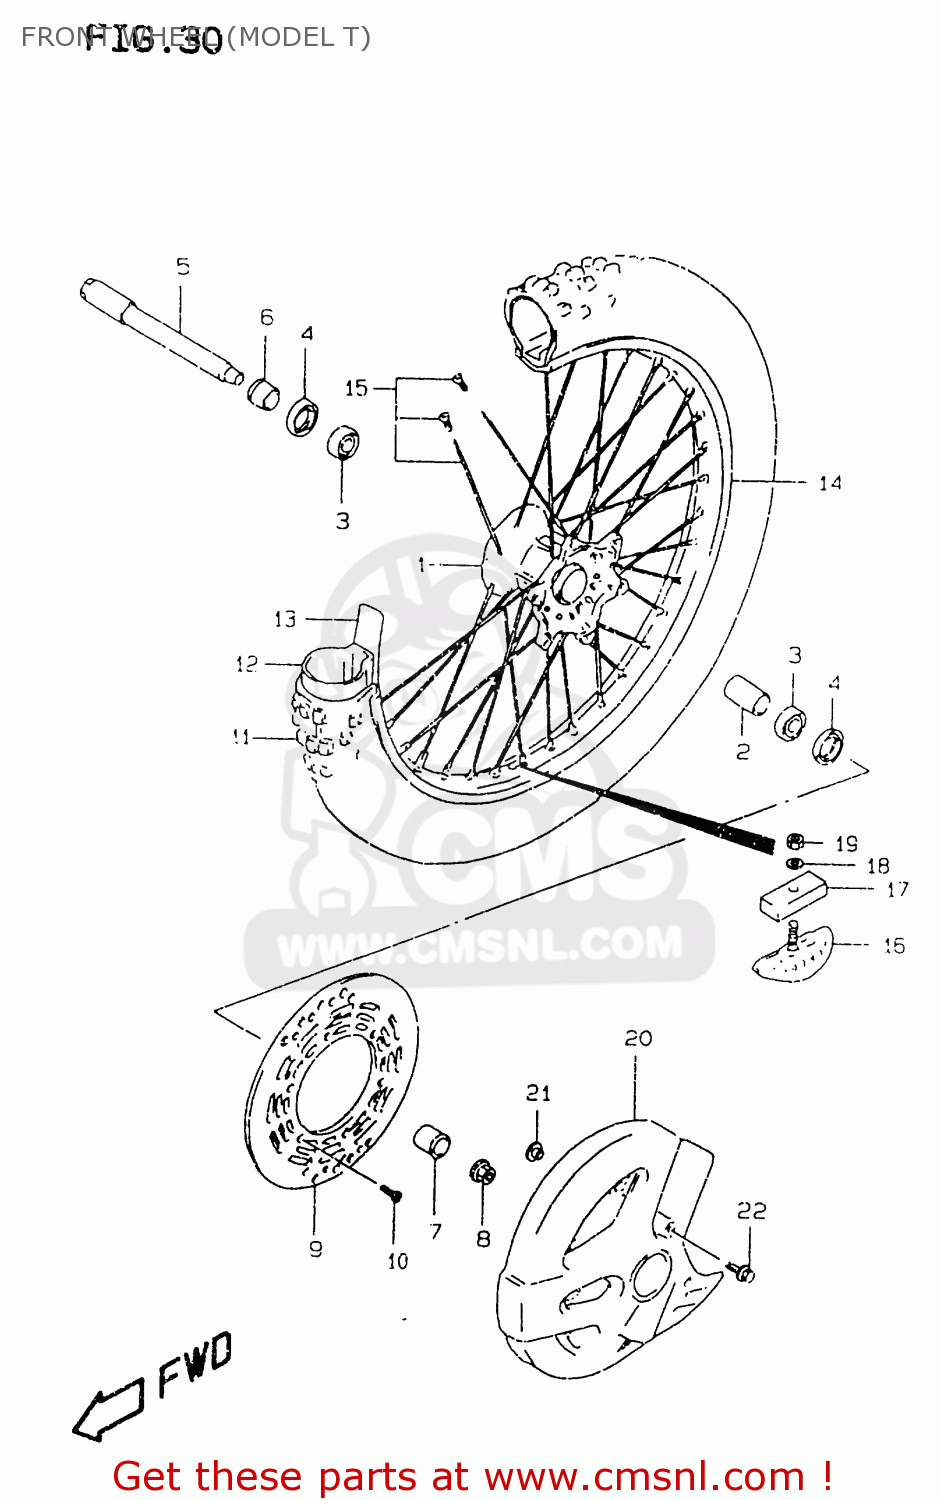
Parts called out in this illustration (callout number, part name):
1	HUB,FR WHEEL
2	SPACER,FR HUB BEARING
3	BEARING
4	SEAL,OIL(25X37X6)
5	AXLE,FRONT
6	SPACER,FRONT AXLE,RIGHT
7	SPACER,FR AXLE,L
8	NUT
9	DISC,FR BRAKE
10	SCREW
11	TIRE,FRONT 80/100-21
12	TUBE
13	PROTECTOR,WHEEL INNER
14	RIM,FRONT WHEEL (1.60X2
15	SPOKE SET,FR WHEEL
16	STOPPER,BEAD
17	CUSHION,BEAD STOPPER
18	WASHER
19	NUT
20	COVER,FRONT BRAKE DISC
21	WASHER
22	BOLT(6X16)
